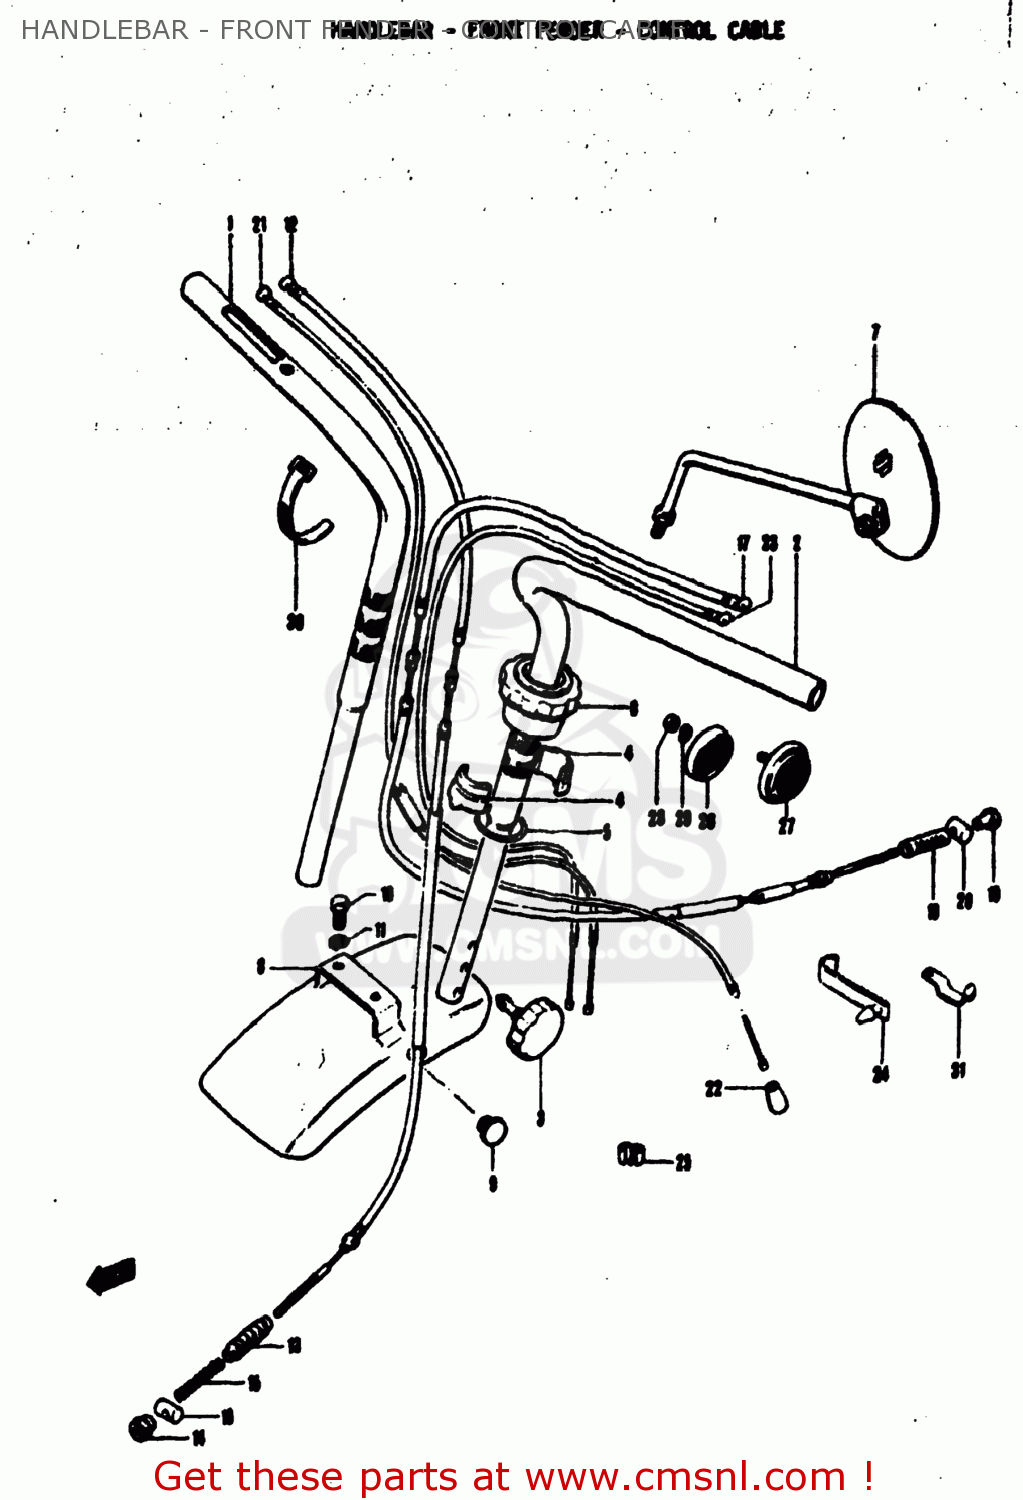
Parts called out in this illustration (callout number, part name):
1	HANDLEBAR, RIGHT
2	HANDLEBAR, LEFT
4	STOPPER, HANDLEBAR
7	MIRROR ASSY, REAR VIEW
10	BOLT
11	LOCK WASHER
12	CABLE, FRONT BRAKE
13	SEAL,DUST(7X16X75)
14	NUT
15	SPRING
16	PIN,10X19
18	SEAL,DUST
19	NUT
20	PIN,10X19
21	CABLE ASSY,THROTTLE
22	SEAL,DUST(7X18X30)
23	CABLE COMP,STARTER
24	BAND
25	CLIP
26	REFLEX REFLECTOR ASSEMBLY
27	REFLEX REFLECTOR ASSEMBLY
28	NUT
29	LOCK WASHER
30	CLAMP
31	CLAMP
